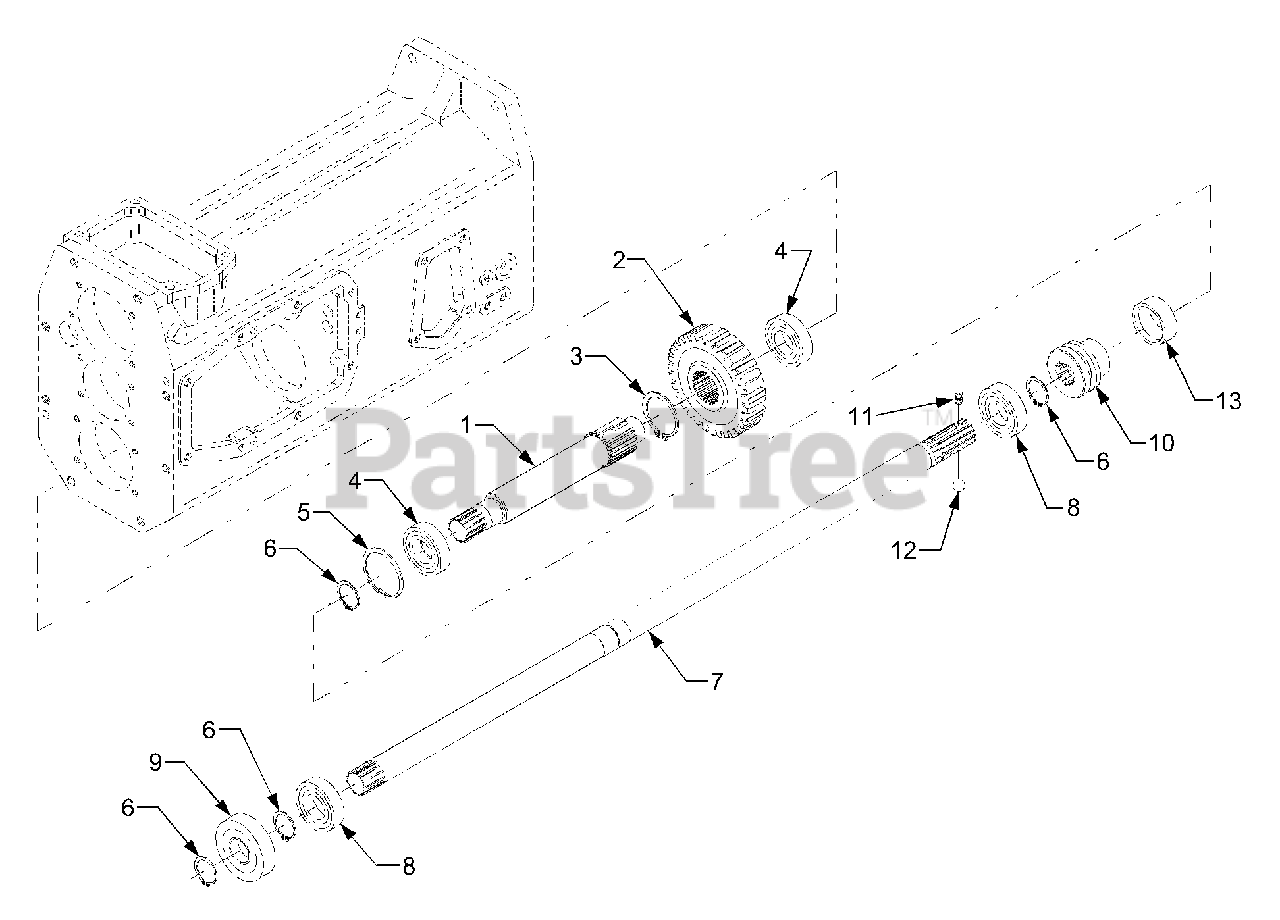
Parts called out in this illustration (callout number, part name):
1	Shaft, Wheel Drive
4	Bearing, Ball
7	Shaft 1, Propeller
8	Bearing, Ball
10	Shift (Front Wheel)
